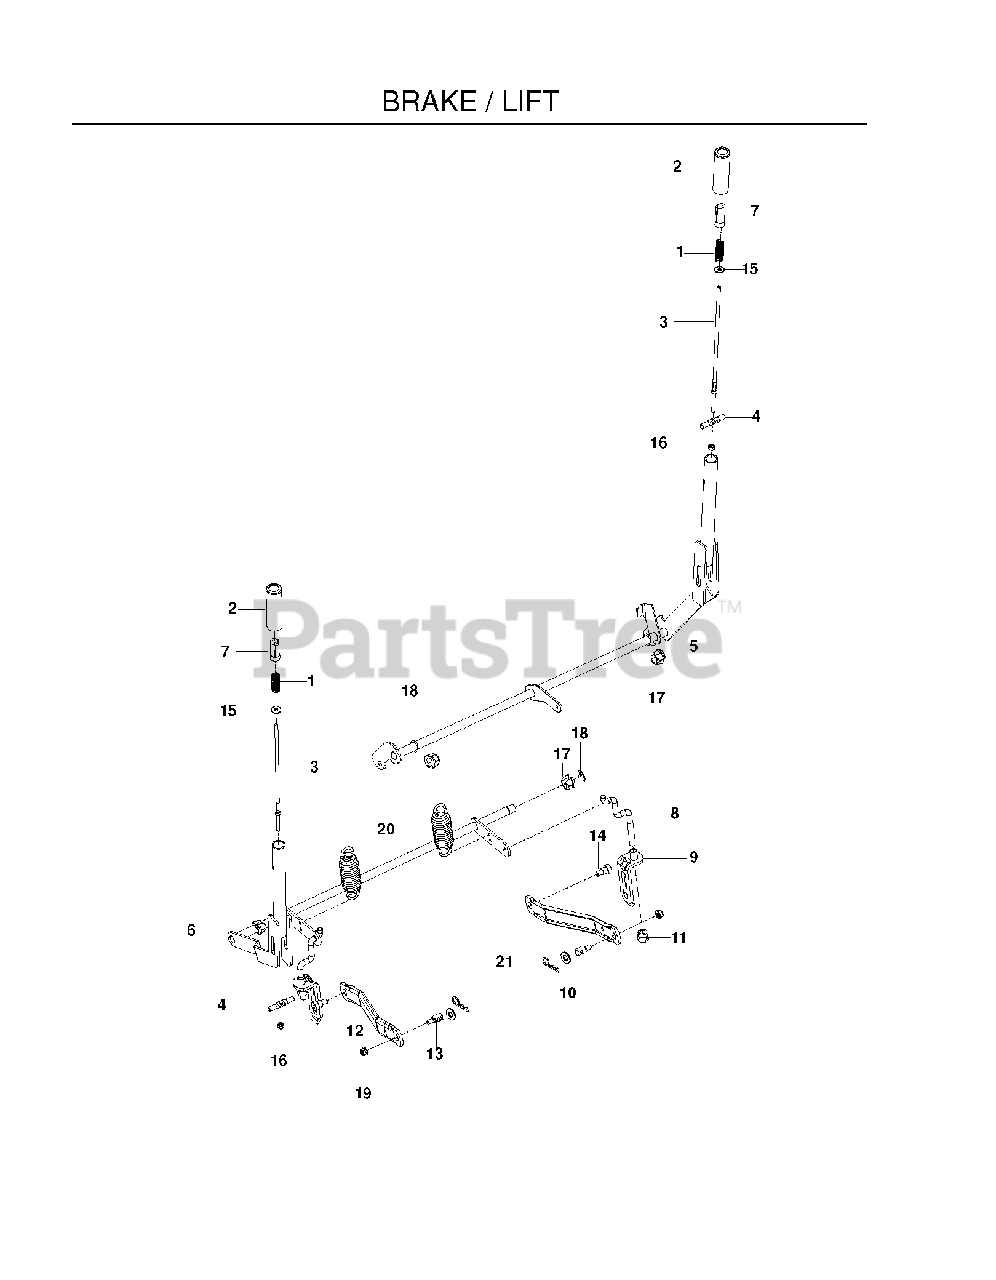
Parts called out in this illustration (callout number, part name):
1	SPRING, COMPRESSION
2	GRIP, HANDLE, BLACK 4"
3	ROD, HANDLE RELEASE
4	RB ROD, LATCH RELEASE
5	SHAFT ASSY, BRAKE, MED, BLK
6	SHAFT.LIFT.MED.BLACK
7	BUTTON, PUSH, BLACK
8	LINK, REAR SUSPENSION
9	ASSEMBLY, BRKT LINK
10	WASHER 5/8 FLAT
11	NUT, LIFT LINK 7/16-20
12	ARM.SUSPENSION.MOWER
13	STUD.FASTNER.W/ANTI-ROTATE
14	SB 3/8-16 X 3/8 SKT HD ZD
15	WASHER 1/4 FLAT
16	RP_NUT 1/4-20 NYLOC
17	PLASTIC NUT
18	E-RING 5/8
19	5/16-18 NYLOC FLANGE NUT
21	HAIRPIN #4
